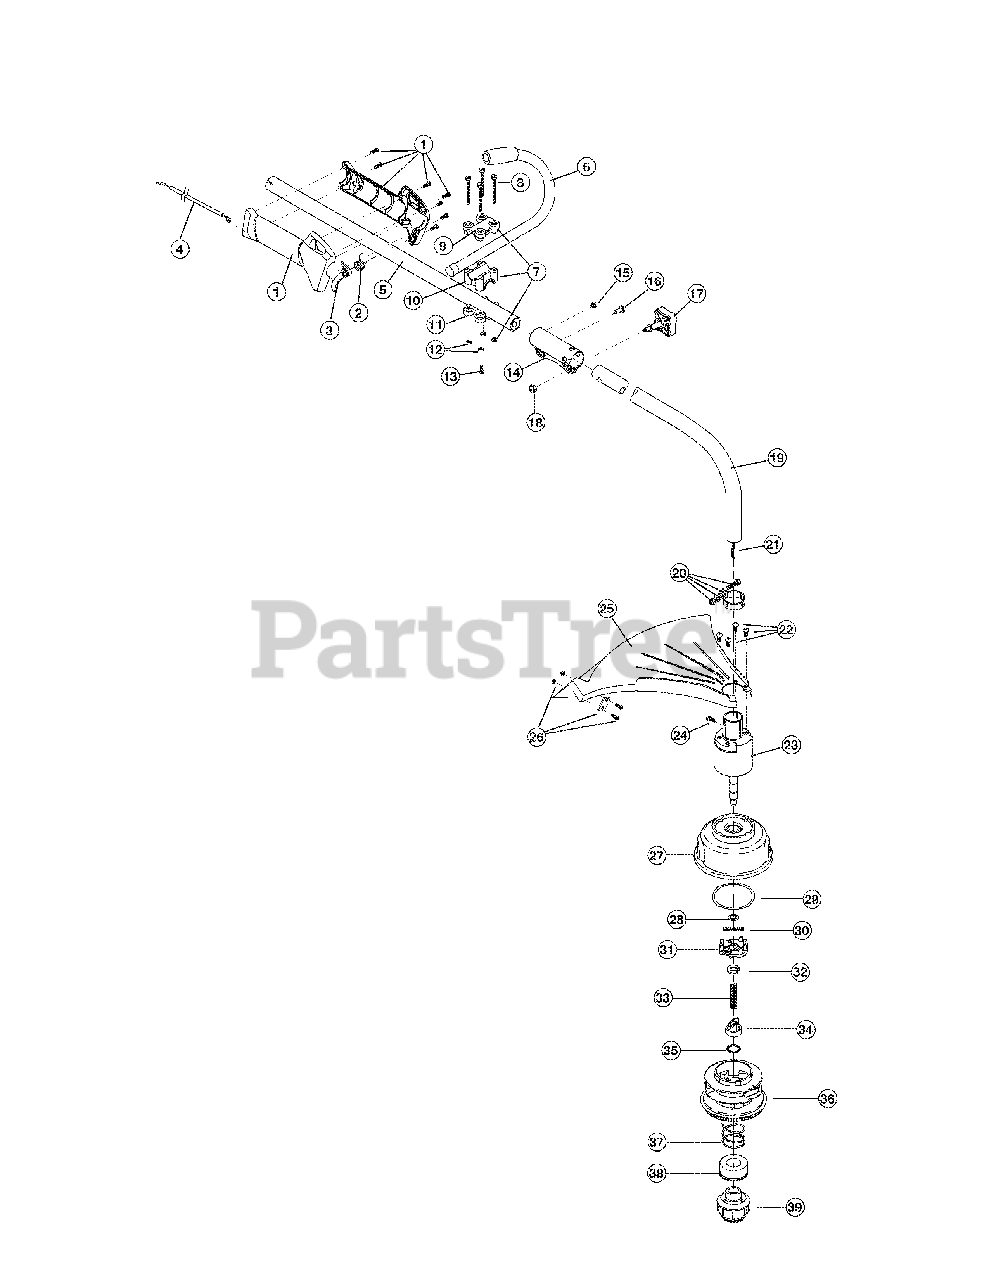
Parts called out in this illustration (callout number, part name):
1	Throttle Housing Assembly (includes 2 & 3)
2	Throttle Trigger Spring
3	Throttle Trigger
4	Throttle Cable
5	Upper Drive Shaft Housing
6	J-Handle Assembly
7	Handle Bracket Assembly (includes 8-13)
9	Upper Handle Clamp
10	Middle Handle Clamp
11	Lower Handle Clamp
13	Anti-Rotation Screw
14	Split Boom Coupler (includes 15-18)
17	Adjustment Knob
18	Knob Retaining Nut
19	Lower Drive Shaft Housing
20	Lower Clamp Assembly
21	Lower Flexible Drive Shaft
22	Shield Mounting Screw
23	Bushing Housing Assembly
24	Anti-Rotation Screw
25	Shield Assembly (includes 26)
26	Blade Assembly
27	Outer Spool Assembly (includes 28)
28	Retainer
29	Thrust Washer
30	Small Spring
31	Slider
34	Plunger
36	Inner Reel
37	Large Spring
38	Foam Seal
39	Bump Head Knob Assembly (includes 37 & 38)
